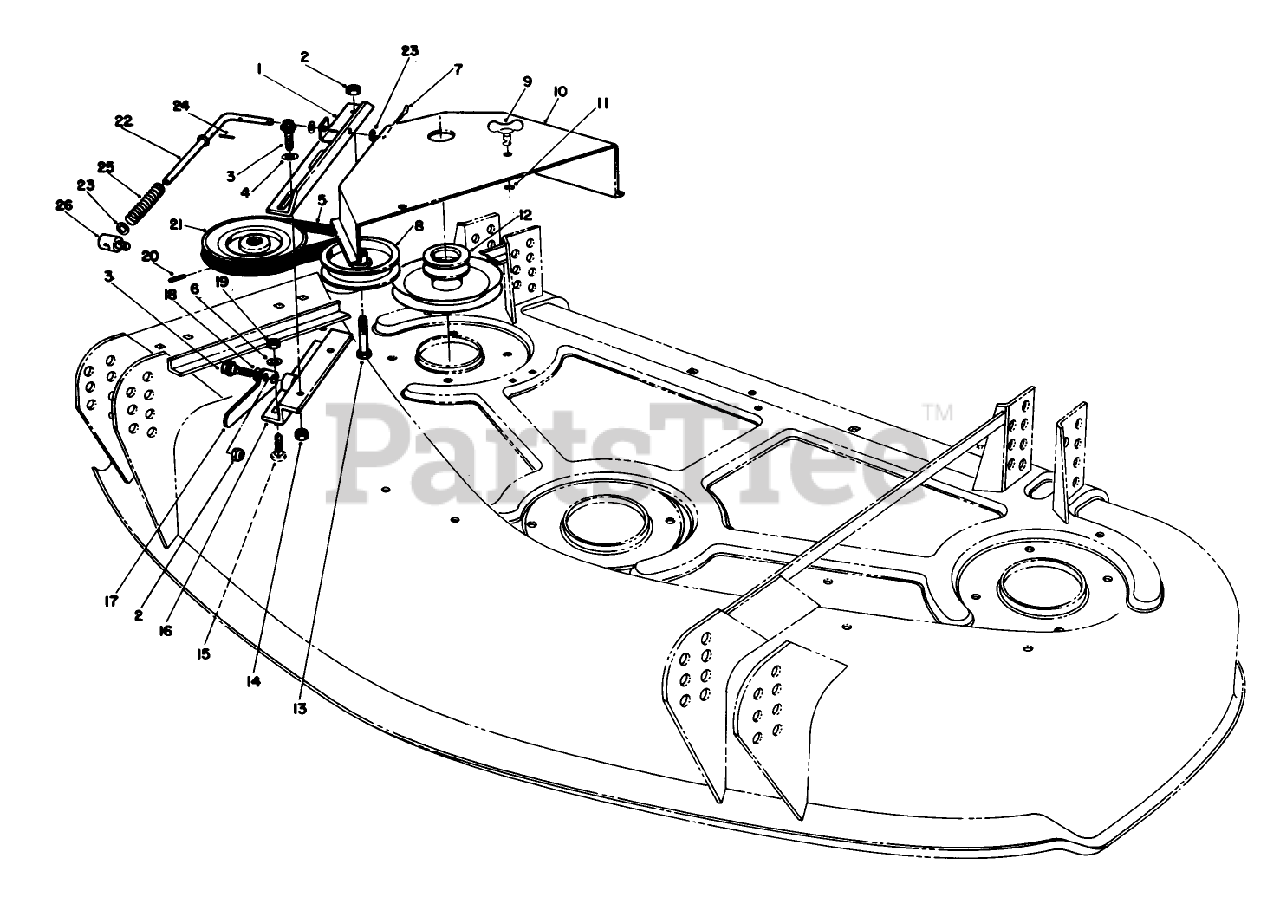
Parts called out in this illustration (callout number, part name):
2	NUT-LOCK, NI
3	SCREW-SHOULDER
4	WASHER-THRUST
5	V-BELT
6	WASHER-PLAIN
7	SCREW-HH
8	PULLEY-IDLER
9	STUD-HEAD, WING
11	RING-RETAINING
12	DECK PULLEY WA
13	SCREW-HH
14	NUT-LOCK, NI
15	SCREW-CARR
18	WASHER-SPRING
19	NUT-KEPS
20	SCREW-HH
22	IDLER ROD WA
23	WASHER-FLAT
24	PIN-ROLL
25	COMPRESSION SPRING
26	BAGGER TRUNNION
